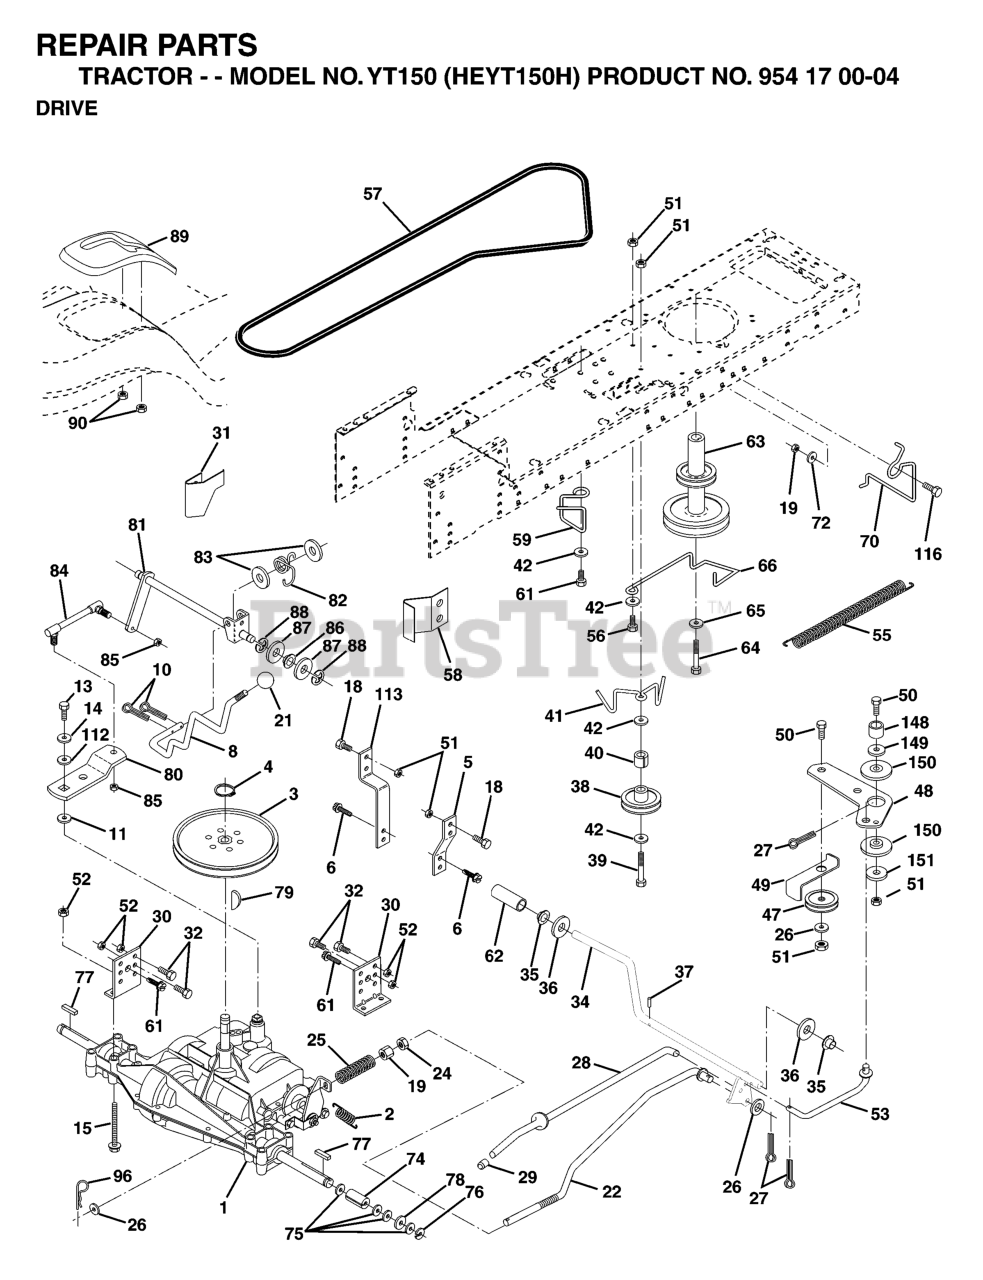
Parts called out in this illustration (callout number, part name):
2	SPRING,BRAKE RETURN
3	PULLEY TRANS
4	RETAINING RING LT
5	STRAP TORQUE
6	SCREW.THDROL.5/16-18X3/4.TTY
8	ROD SHIFT FENDER
10	PIN COTTER
11	WASH-SHFT PLT LT
13	BOLT 1/4-28X3/4
14	LOCKWASHER
15	BOLT HEX 5/16-18 GR 5
19	NUT
21	KNOB.DUCKHEAD.1/2
24	NUT
25	SPRING ROD LT
26	WASHER
27	COTTER PIN
28	ROD BRAKE PARK LT
29	PLUNGER CAP
30	BRACKET TRANSAXLE
31	KEEPER BELT LH
32	BOLT
34	SHAFT, FOOT PEDAL
35	BEARING.NYLON
37	DRIVE PIN
38	PULLEY.IDLER.FLAT
41	KEEPER, BELT IDLER
42	WASHER
47	IDLER PULLEY
48	BELLCRANK, CLUTCH
49	RETAIN BELT
50	BOLT
52	LOCKNUT
53	LINK, CLUTCH LT
55	SPRING, RETURN LT
57	V-BELT
59	KEEPER CENTER SPAN
61	SCREW
62	COVER, PEDAL (1 2)
63	PULLEY.ENG.CL.MECH.SLVR.LT/YT
64	BOLT
65	LOCKWASHER
66	KEEPER BELT ENGINE
70	KEEPER BELT ENG
72	WASHER
74	SPACER AXLE
77	SQUARE KEY
79	KEY STD (1373) DANA
82	SPRING,TORSION
83	WASHER
84	ROD TIE 20"
85	NUT LOCK CENTER 1/4 -28 FNTHD
89	SHIFT CONSOLE
90	NUT.PUSH.3/16
96	RETAINER M
113	STRAP TORQUE LH LT
116	BOLT
151	Washer 13/32 x 2 x 10 Ga.
